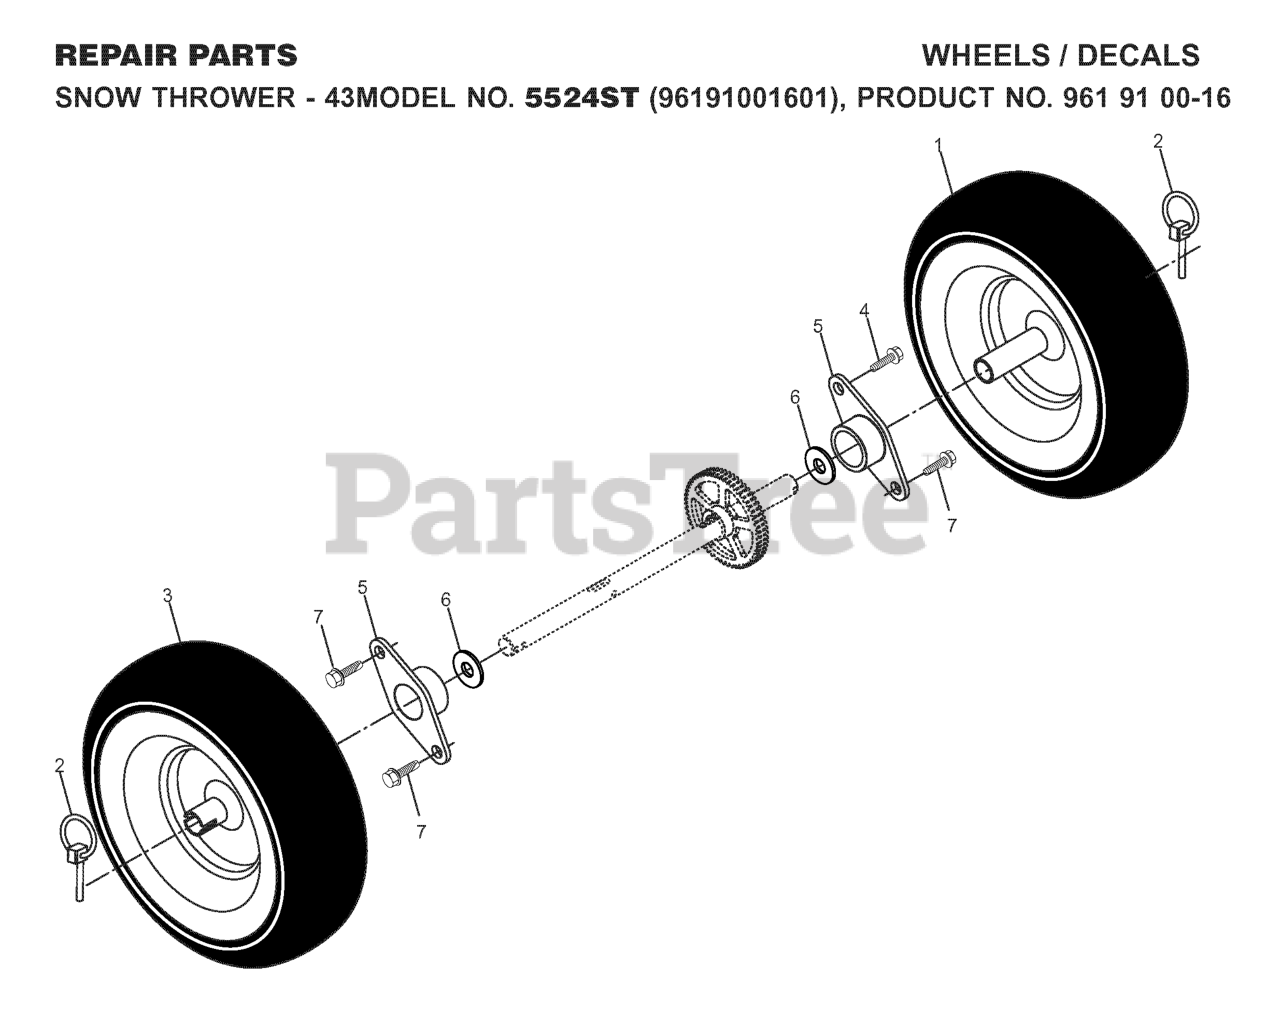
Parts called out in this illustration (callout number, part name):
1	WHEEL.ASM.LT.16"GRY.XTRAC
2	PIN KLIK, 1/4
3	WHEEL.ASM.RT.16".GRAY.XTRAC
5	BEARING, AXLE
6	WASHER TRUST 1"
